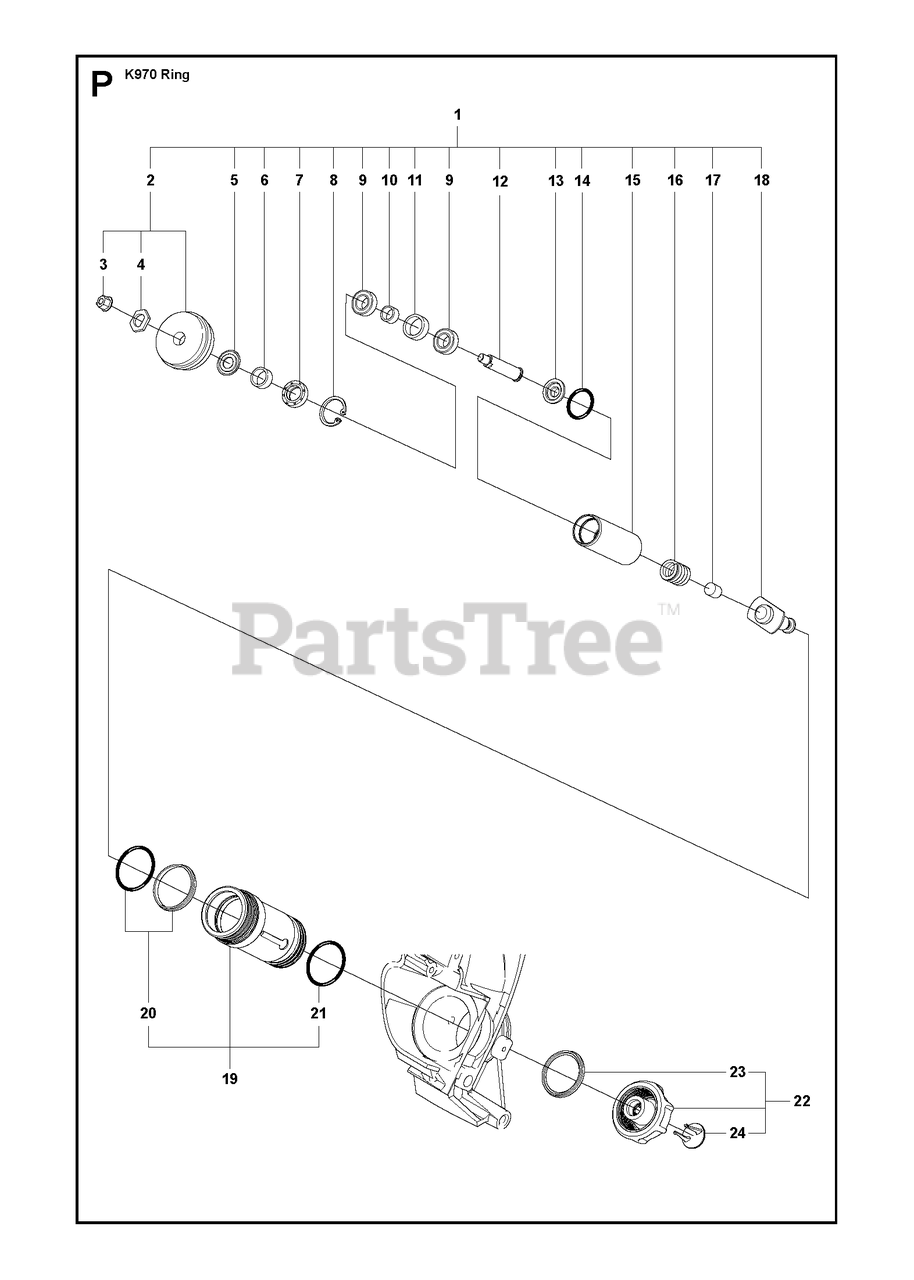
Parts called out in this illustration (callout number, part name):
1	BEARING CAGEIncl. 2, 5 - 18
2	GUIDE ROLLERIncl. 3, 4
9	BALL BEARING
19	SLEEVEIncl. 20, 21
